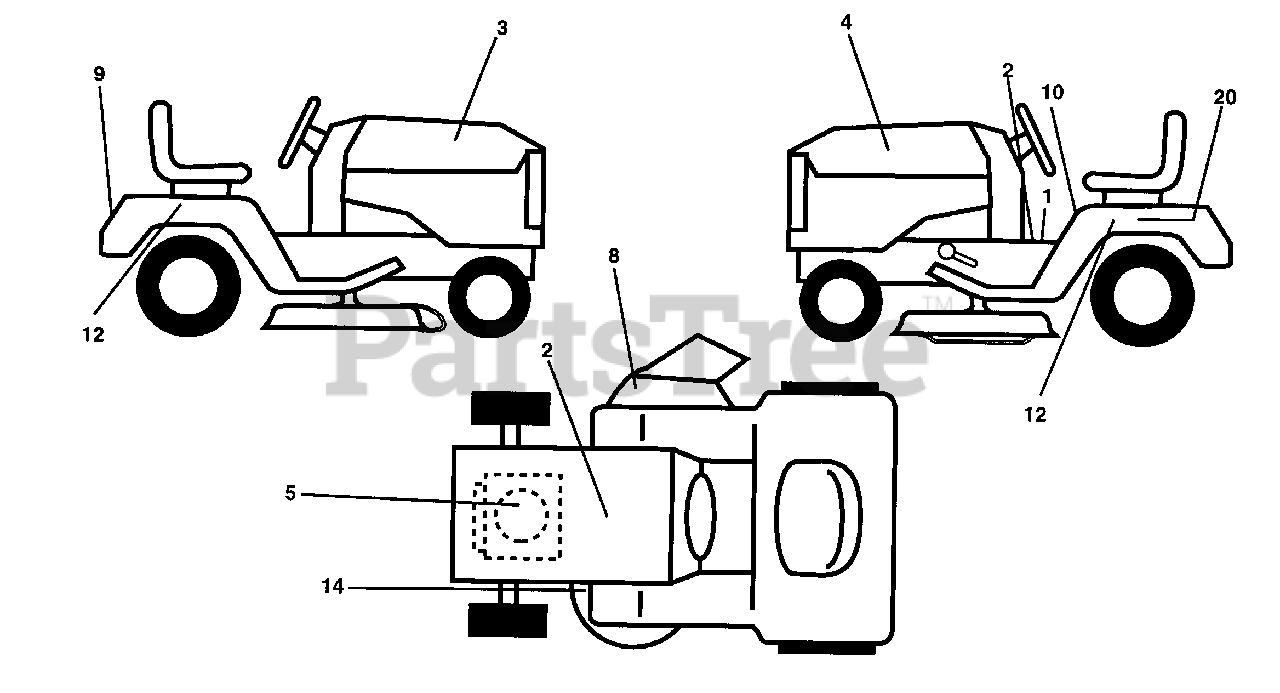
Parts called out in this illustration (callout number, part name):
1	Decal Oper. Step Thru E/F
2	Decal Battery
3	Decal Hood LH
4	Decal Hood RH
5	Decal HP Engine
8	Decal Warning Multi-Languages
9	Decal Fender Husq
10	Decal Fender Danger E/F
12	Decal Fender Auto Husq Radius
14	Decal V-Belt Schematic
